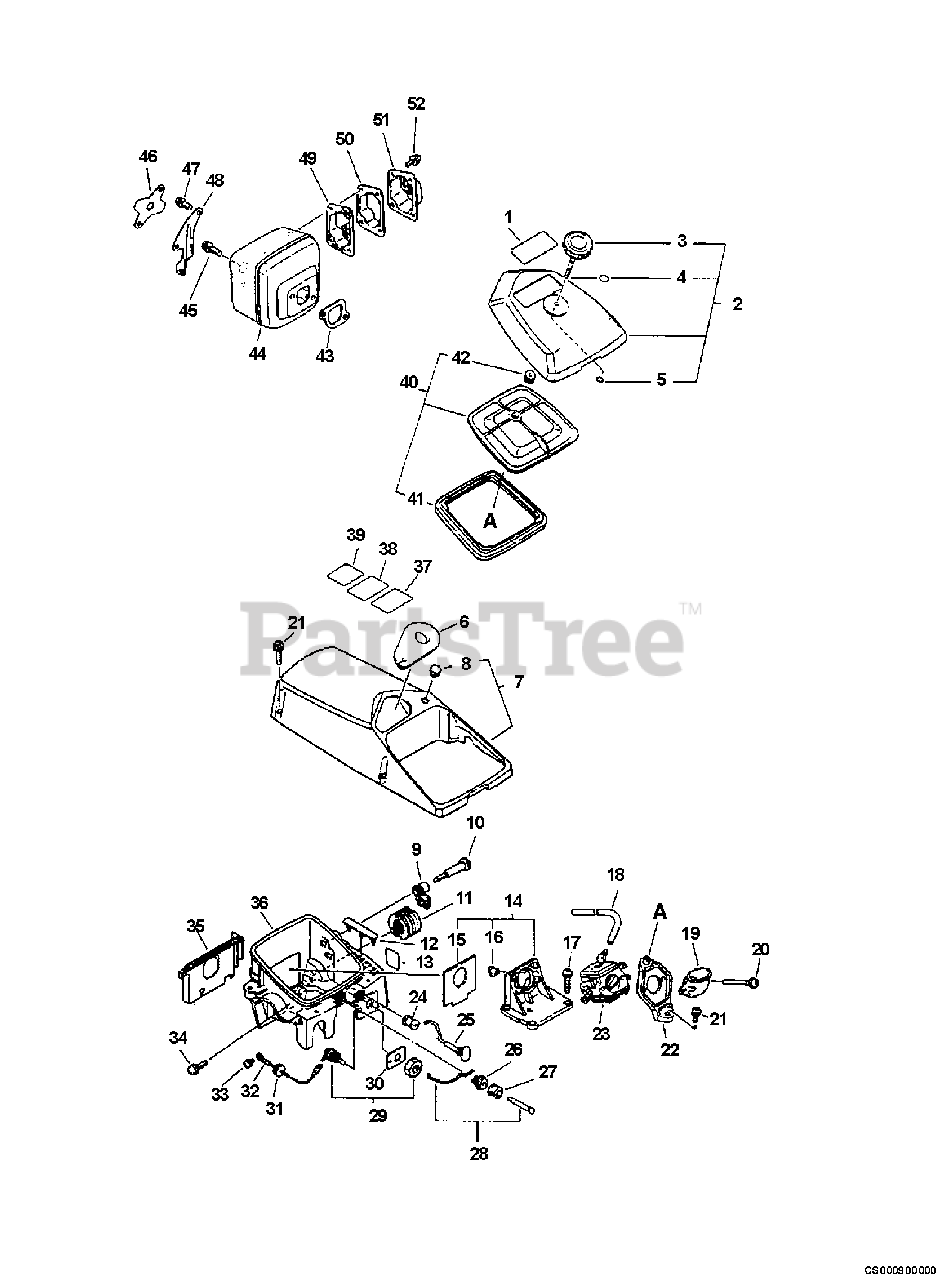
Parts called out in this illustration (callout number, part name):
1	LABEL - MODEL CS-8000
2	AIR FILTER COVER ASSY
3	THUMBSCREW
4	O-RING - 10
5	O-RING - 3
6	PLATE, GUIDE
7	ENGINE COVER KIT - GRAY
10	SCREW, IDLE ADJUST
12	PLUG
14	INSULATOR, INTAKE
15	SEAL, DUST
16	NUT
17	SCREW - 5X25
18	PIPE - IMPULSE
19	PLATE, PREVENT
20	SCREW - 5X55
21	SCREW - 5X20
22	BRACKET, AIR CLEANER
23	CARBURETOR HDA-153A
23	CARBURETOR HDA-153B
25	ROD, CHOKE
26	GUIDE, THROTTLE ROD
28	ROD, THROTTLE
29	IGNITION SWITCH ASSY
30	LABEL - STOP
32	LEAD - GROUND
33	SCREW - 4X8
34	SCREW - 4X8
35	PLATE, GUIDE
36	CASE, CARBURETOR
37	LABEL - KICK BACK
38	LABEL - BAR & CHAIN
39	LABEL - KICK BACK
40	FILTER, AIR
43	GASKET, EXHAUST
45	SCREW - 6X20
46	COVER, MUFFLER
47	SCREW - 5X14
48	BRACKET, MUFFLER
49	SCREEN, SPARK ARRESTOR
50	GUIDE, EXHAUST - INNER
51	GUIDE, EXHAUST - OUTER
52	SCREW - 4X10
